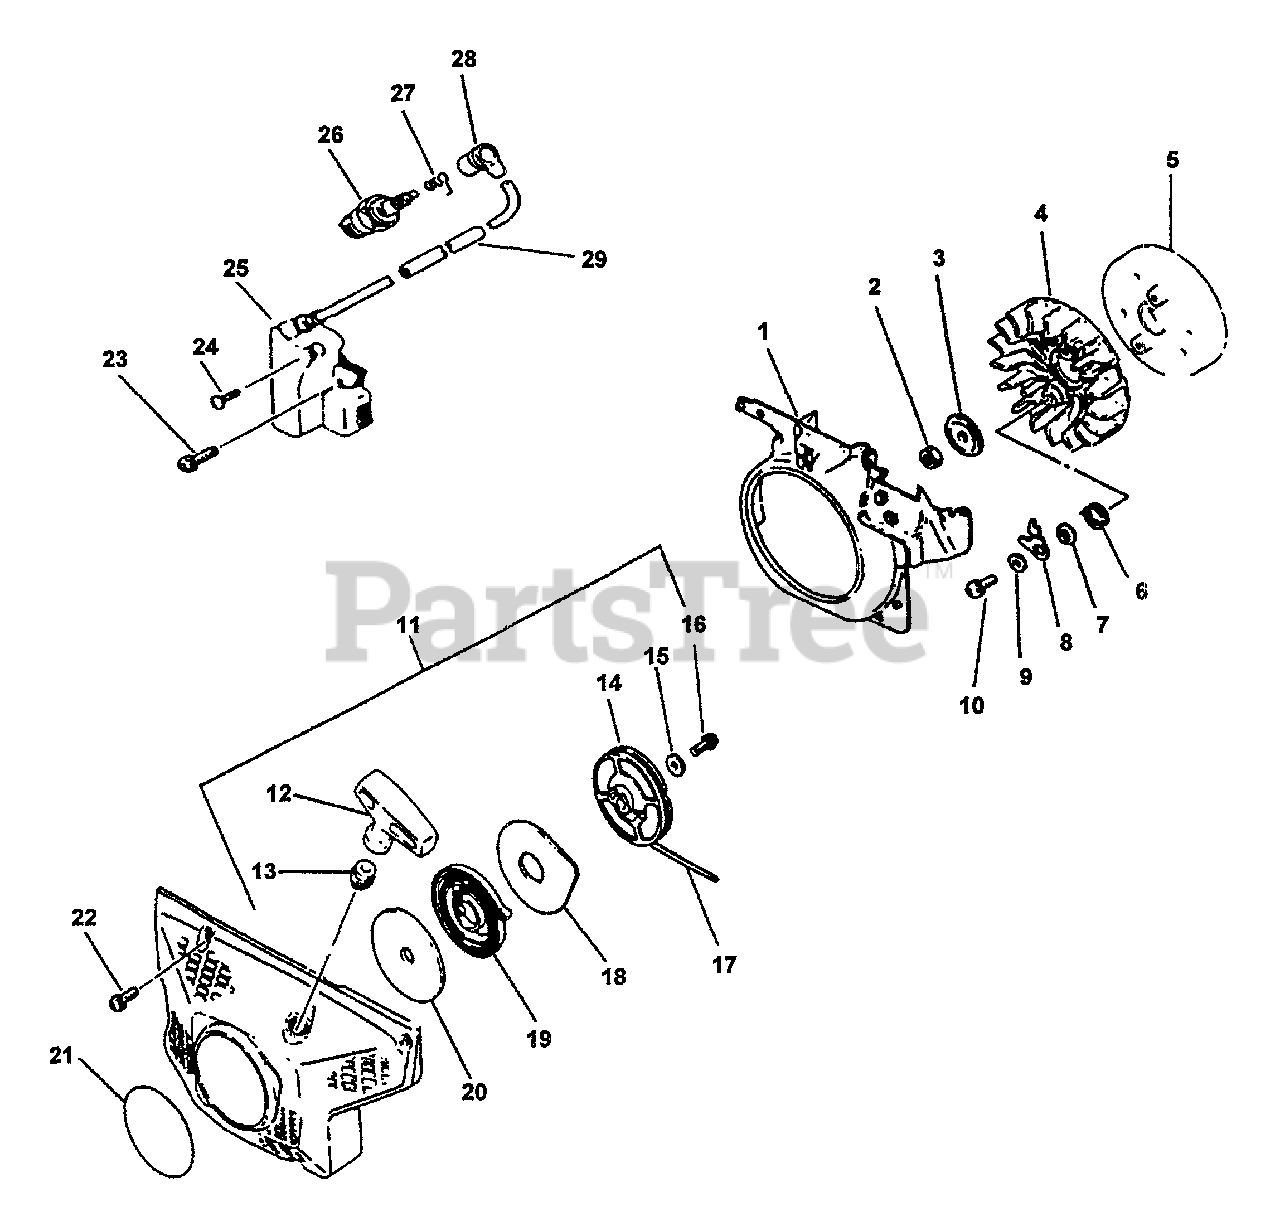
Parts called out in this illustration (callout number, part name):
1	SHIELD, FAN
3	WASHER - CUP
5	FLYWHEEL
6	SPRING, RETURN
8	PAWL, STARTER
9	WASHER - 5
10	SCREW - 5X14
11	STARTER ASSY
12	GRIP, STARTER
13	GUIDE, ROPE
14	REEL, ROPE
15	WASHER - 5
16	SCREW - 5X14
17	ROPE, STARTER - 4X950
18	PLATE, STARTER
19	SPRING, REWIND
20	PLATE, STARTER
21	LABEL - ECHO
22	SCREW - 5X20
23	SCREW - 4X20
24	SCREW - 4X8
25	COIL, IGNITION
26	SPARK PLUG -- BPM-7A
27	TERMINAL, SPARK PLUG CAP
28	CAP, SPARK PLUG
29	TUBE
